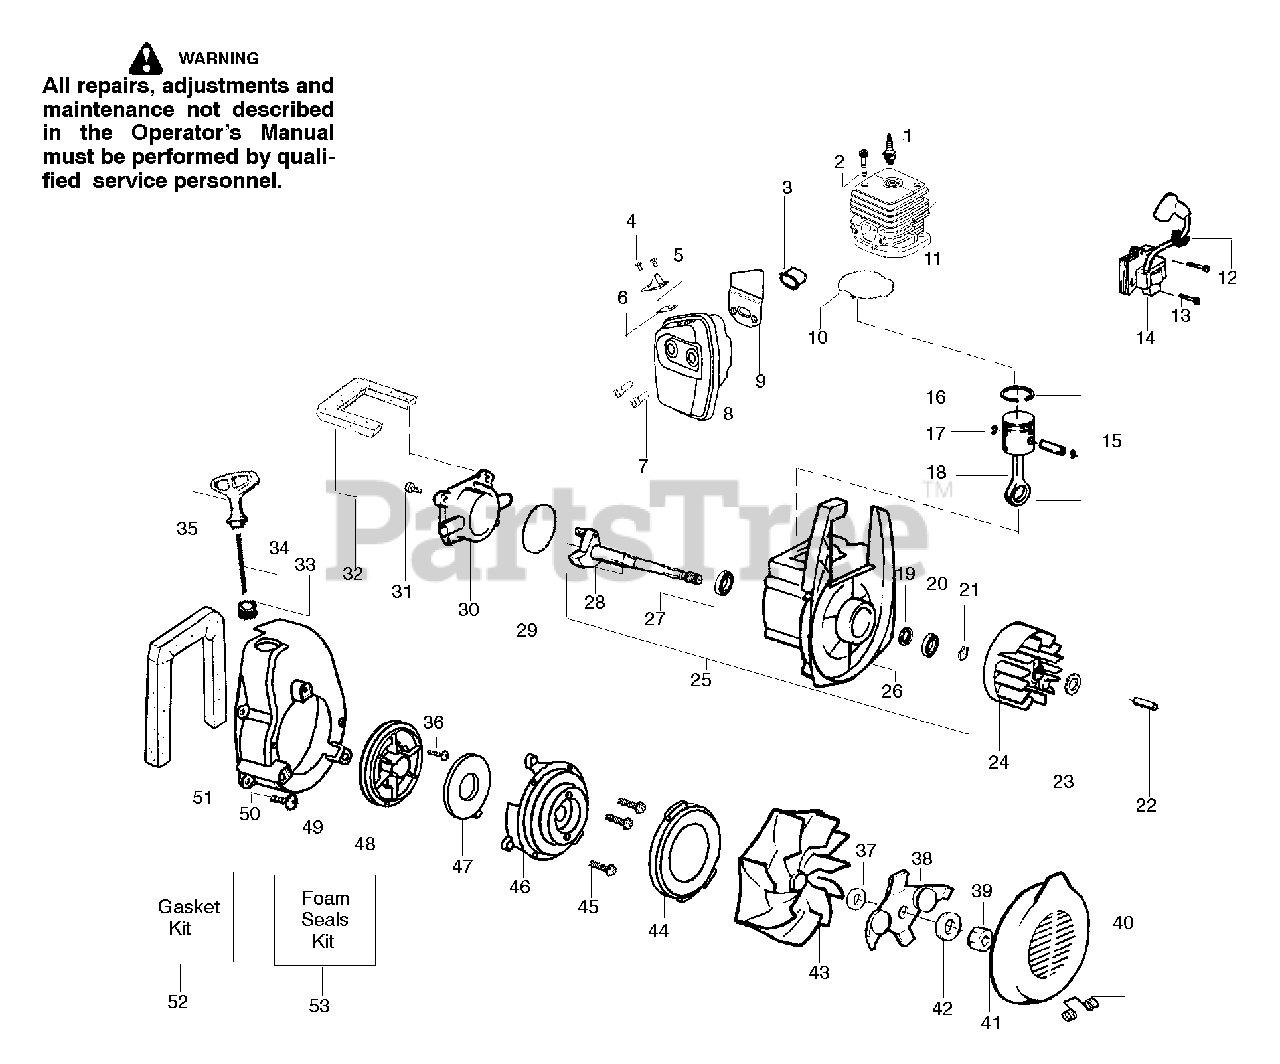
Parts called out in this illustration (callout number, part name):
1	Spark Plug (RCJ-6Y)
3	Insulator-Heat
5	Deflector-Muffler
6	Kit-Spark Screen
7	Screw-Muffler-Internal
8	Kit-Muffler
9	Gasket-Baffle (kit)
10	Gasket-Cylinder (kit)
11	Kit-Cylinder
12	Grommet-Ign. Module
13	Screw-Ignition Module
14	Module-Ignition
15	Kit-Piston
16	Ring-Piston
17	Retainer-Piston Pin
18	Assy-Connecting Rod
19	Seal-Crankcase
20	Bearing-Outer
21	Retainer Ring-C'chaft
22	Spacer-Flywheel
24	Assy-Flywheel
25	Assy-Crankcase/Crank shaft
26	Assy-Crankcase
27	Bearing-Inner
28	Assy-Crankshaft
29	O-ring-C/case (kit)
30	Cover-Crankcase
31	Screw
32	Foam-219mm (kit)
33	Eyelet-Flange
34	Kit-Rope
35	Handle-Starter
36	Screw-Rope
37	Washer-Belleville
38	Assy-Mulch Blade (BV2000 Only)
40	Spring-Return Cover
41	Door-Inlet
42	Washer (BV1850 only)
43	Kit-Impeller Assy
44	Seal-Ring
46	Housing-Pulley
47	Spring-Starter
48	Kit-Starter Pulley
49	Housing-Fan
50	Screw
51	Foam-365mm (kit)
52	Kit-Gasket
53	Kit-Foam Seals
